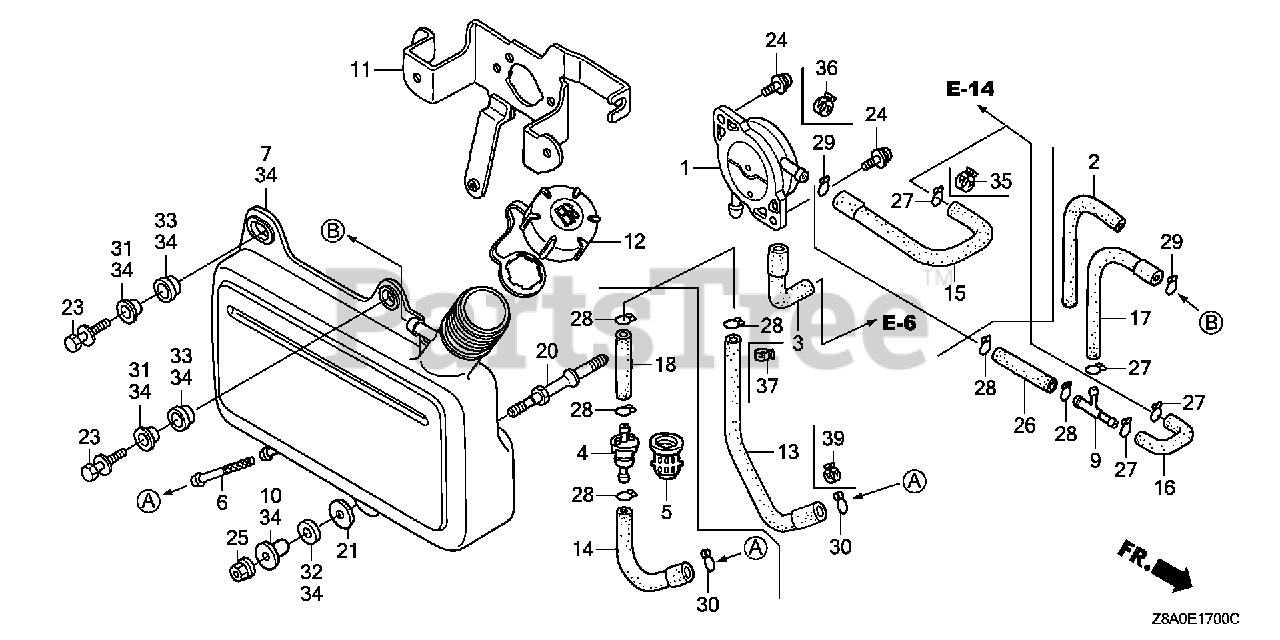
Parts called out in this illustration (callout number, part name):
1	PUMP ASSY., FUEL
3	TUBE, DIAPHRAGM
6	FILTER, FUEL
7	TANK, FUEL
10	COLLAR, FUEL TANK SETTING
11	STAY A, FUEL TANK
12	CAP ASSY., FUEL TANK
13	TUBE, FUEL TANK
13	TUBE, FUEL TANK (FKM) (NA USE ALT:17701-ZL8-000)
15	TUBE, FUEL
15	TUBE, FUEL (FKM)
20	BOLT, FUEL TANK STUD (H=30MM)
21	WASHER (6MM)
23	BOLT-WASHER (6X25)
24	SCREW-WASHER (5X14)
25	NUT, FLANGE (6MM)
27	CLIP, TUBE (B8)
28	CLIP, TUBE (B10)
29	CLIP, TUBE (C9)
30	CLIP, TUBE (C11)
31	COLLAR, TANK SET
32	RUBBER A, TANK MOUNTING
33	RUBBER B, TANK MOUNTING
34	TANK KIT, FUEL
35	CLAMP, TUBE (D8)
36	CLAMP, TUBE (D8.5)
37	CLAMP, TUBE (D10)
39	CLAMP, TUBE (D12)
